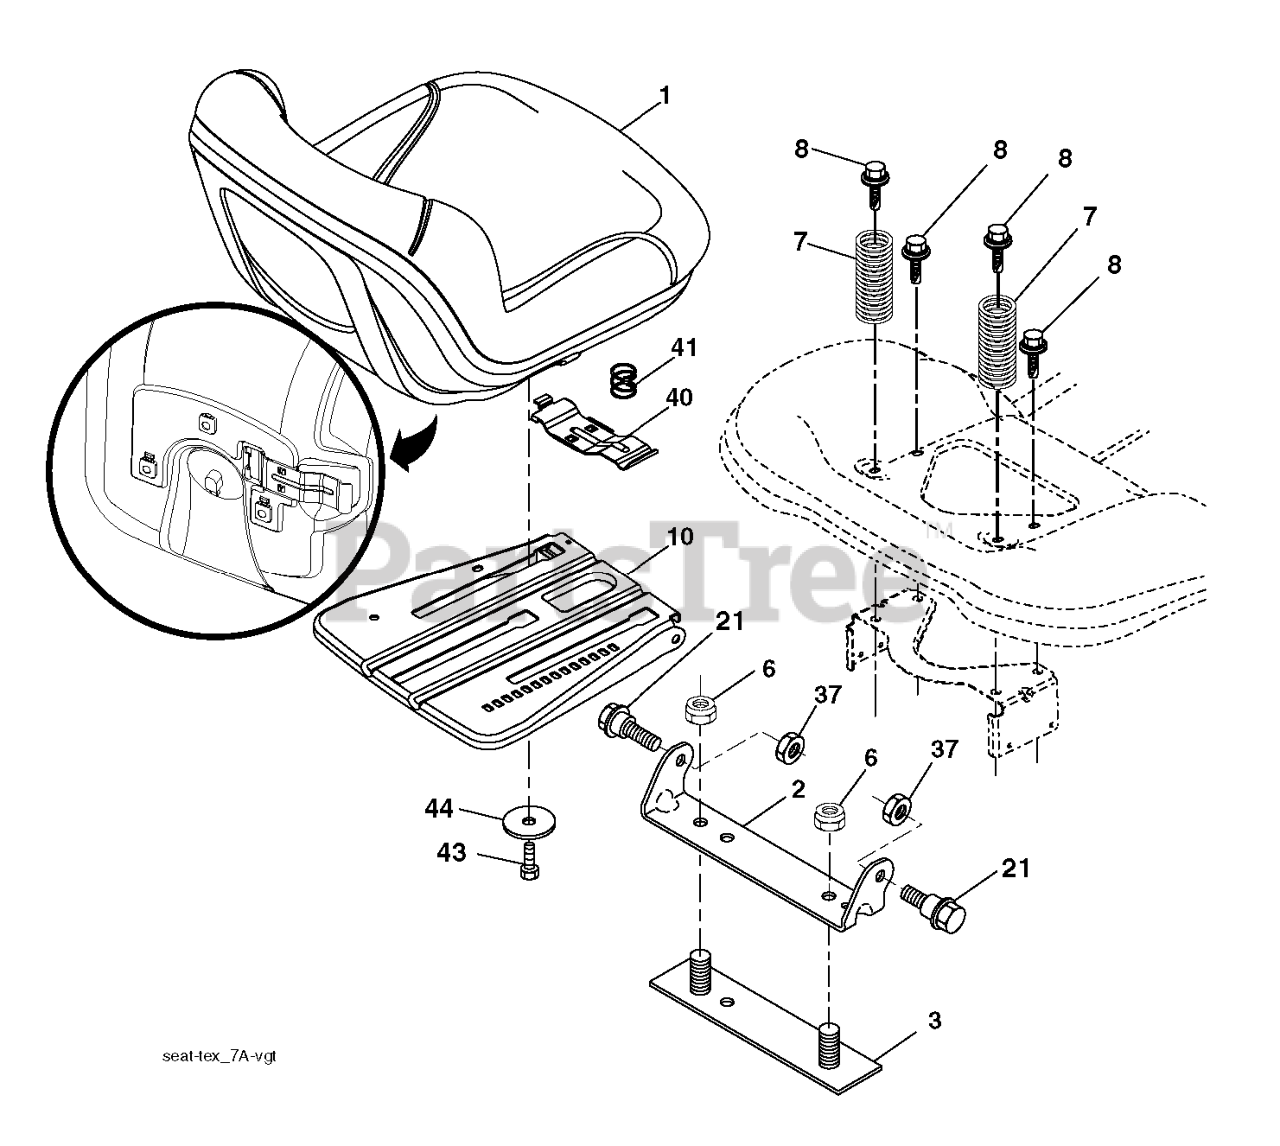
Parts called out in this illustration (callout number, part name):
1	SEAT.TH130.GRY.MILSCO.
2	BRKT.PIVOT.FENDER
3	STRAP
6	NUT
7	SPRING COMPRESSION
8	BOLT.5/16-18UNCX3/4 W/SEMS.BLK
10	PAN.ASM.SEAT.3PT
21	BOLT.SHOULDER.5/16-18
37	NUT.71038.31-18.HEX.NYLOCK
40	HANDLE.SLIDE.SEAT.TEX.BLACK
41	SPRING.LATCH.SEAT.TEX
44	WASHER 13/32 X 2-3/8 X 12GA
